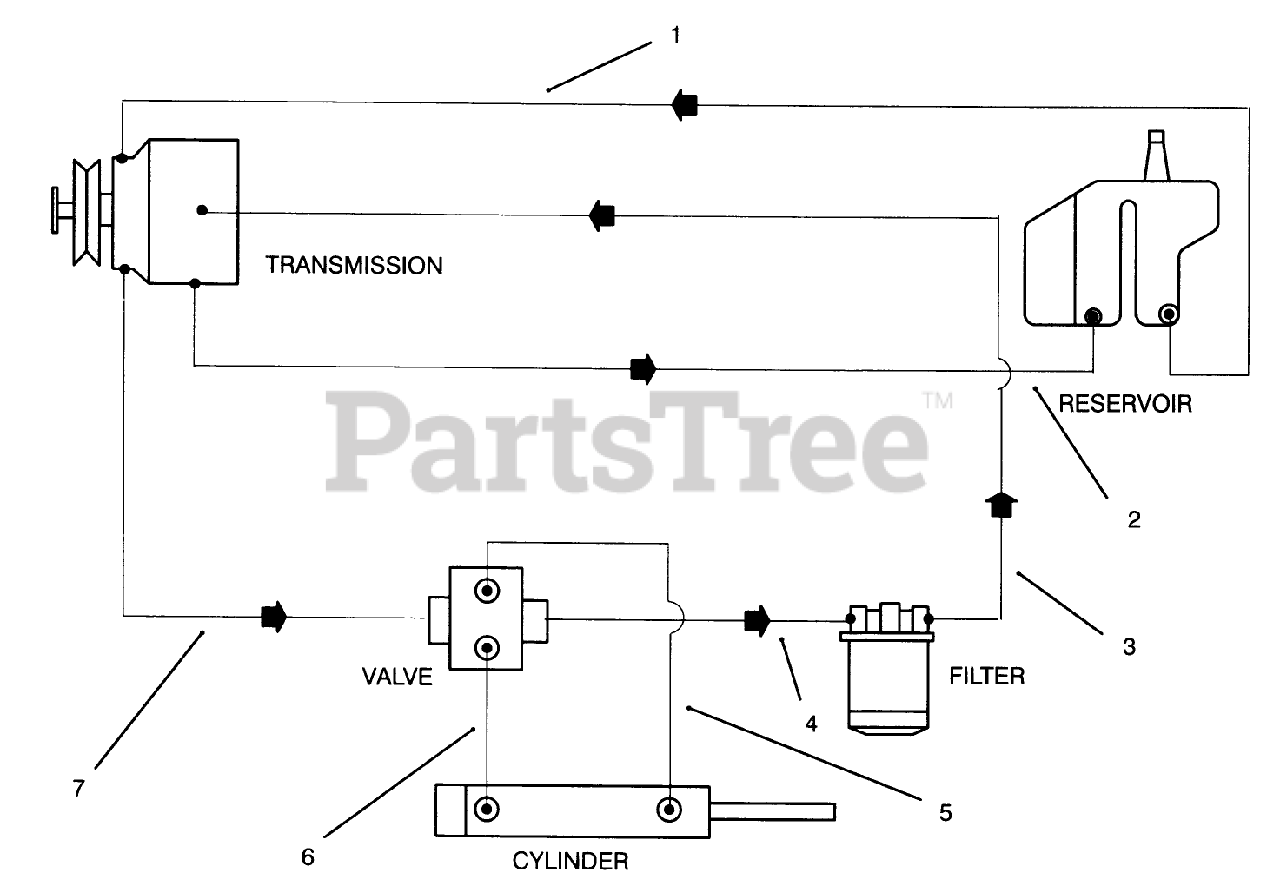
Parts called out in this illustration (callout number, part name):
1	HOSE ASM
2	TUBE ASM
3	HOSE ASM
4	HOSE ASM
5	HOSE ASM
6	HOSE ASM
7	HOSE ASM
